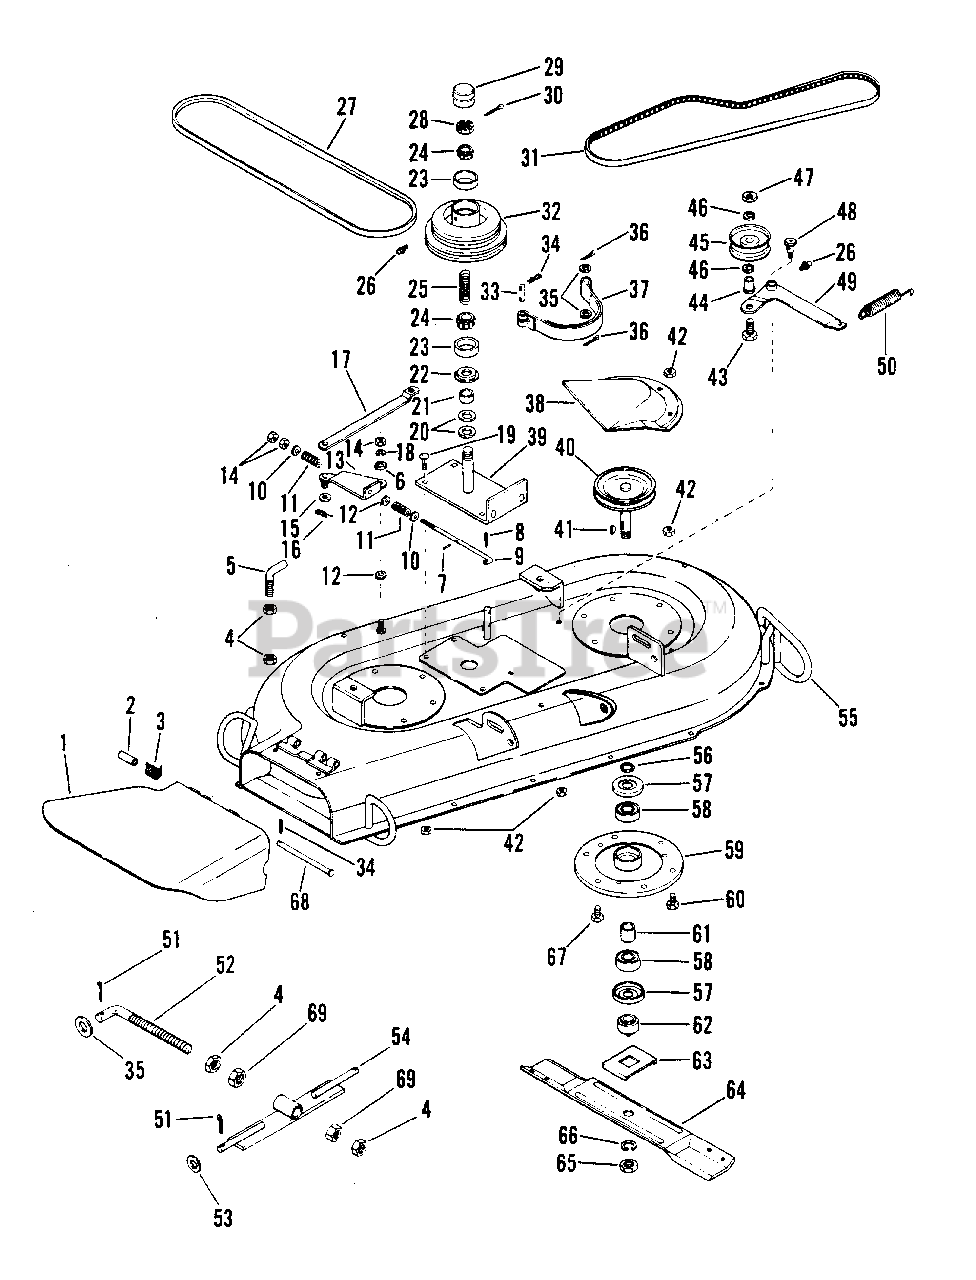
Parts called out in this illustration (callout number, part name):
1	CHUTE, DEFLECTOR
2	BUSHING
3	SPRING, TORSION
4	NUT, JAM 1/2-13 HEX
5	HOOK, HANGER
6	SPACER
7	PIN, SPRING .125X.750
8	PIN, COTTER .06X.50
9	ROD, BRAKE
10	WASHER, FLAT .312X.734X.065
11	SPRING
12	WASHER, FLAT .406X.812X.065
13	LEVER, BRAKE
14	NUT, LOCK 5/16-18
15	WASHER, FLAT .406X.812X.065
16	HAIR PIN, INTERNAL
17	LINK
18	WASHER, FLAT
19	BOLT, CARRIAGE 3/8-16X.75
20	WASHER, FLAT .813X1.37X.100
21	SPACER
22	SEAL
23	CUP, BEARING
24	CONE, BEARING
25	SPRING, COMPRESSION
26	FITTING, ZERK
27	BELT, MOWER
28	NUT, SLOTTED JAM
29	CAP
30	PIN, COTTER .125X1.25
31	BELT
32	SHEAVE
33	PIN
34	PIN, COTTER .09X.75
35	WASHER, FLAT .531X1.062X.095
36	PIN, COTTER .09X1.00
37	BAND, BRAKE
38	COVER
39	PLATE, DRIVE
40	SHEAVE, 4.00
41	KEY, WOODRUFF .187X.75 #9
42	NUT, LOCK 3/8-16
43	BOLT, HEX 1/2-13X1.25
44	BUSHING, FLANGE
45	PULLEY, IDLER
46	WASHER, FLAT .52X.81X.033
47	NUT, LOCK 1/2-13
48	BOLT, SHOULDER
49	ARM, IDLER
50	SPRING, DRIVE
51	PIN, COTTER .125X1.00
52	LINK, ADJUSTMENT
53	WASHER, FLAT .500X.250X.083
54	PLATE, ADJUSTMENT
55	DECK, 38" MOWER
56	WASHER, FLAT .812X1.496X.134
57	SLINGER, BEARING
58	BEARING, RADIAL
59	HOUSING, SPINDLE
60	BOLT, HEX 3/8-16X.75
61	SPACER
62	HUB, RETAINER
63	TRAY, BLADE
64	BLADE, MOWER
65	NUT, JAM 3/4-10 HEX
66	WASHER, LOCK 3/4 HEAVY
67	BOLT, HEX 3/8-16X1.00
68	PIN, HINGE
NS	DECAL, DANGER FOOT
NS	DECAL, NO STEP
NS	DECAL, CAUTION
NS	DECAL, WARNING EYE
NS	DECAL, DANGER HAND
